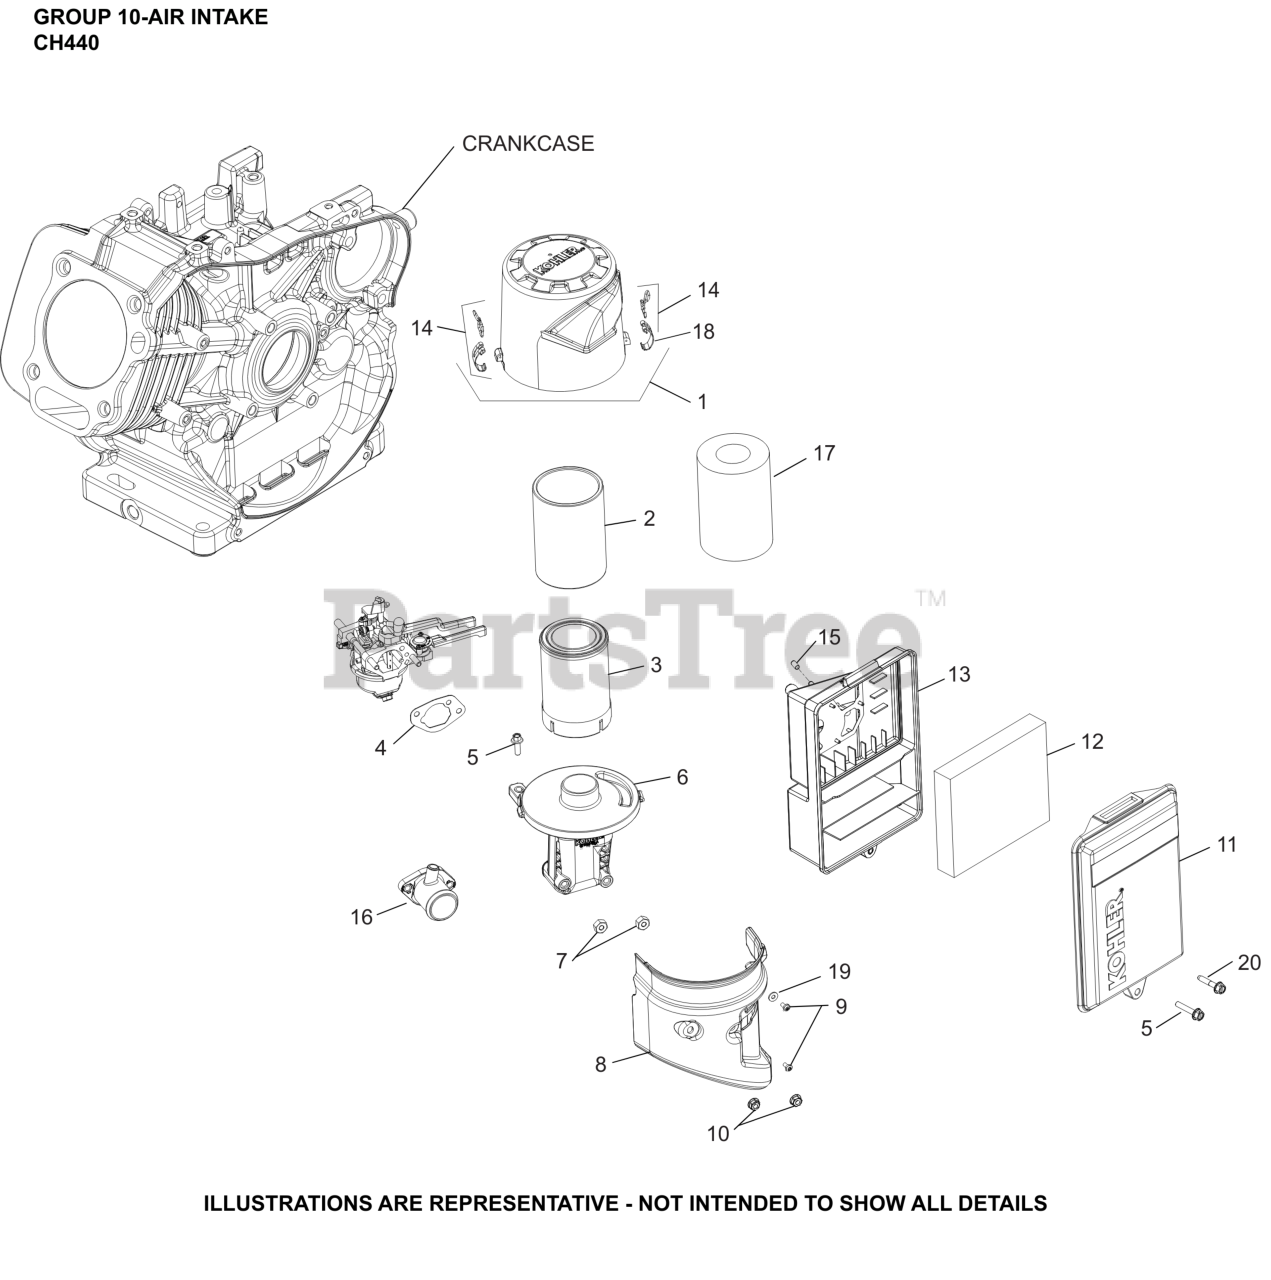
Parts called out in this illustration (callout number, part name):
1	COVER, AIR CLEANR ASSEMBLY
2	ELEMENT, PRE-CLEANER
3	ELEMENT, AIR FILTER
4	GASKET, AIR CLEANER
6	AIR CLEANER BASE ASSY
7	NUT, HEX (M6 THREAD, M8 BODY)
8	COVER, A/C/ BASE CH440
9	SCREW,COVR TO BLWR HOUSING
14	KIT, LATCH CLIP
